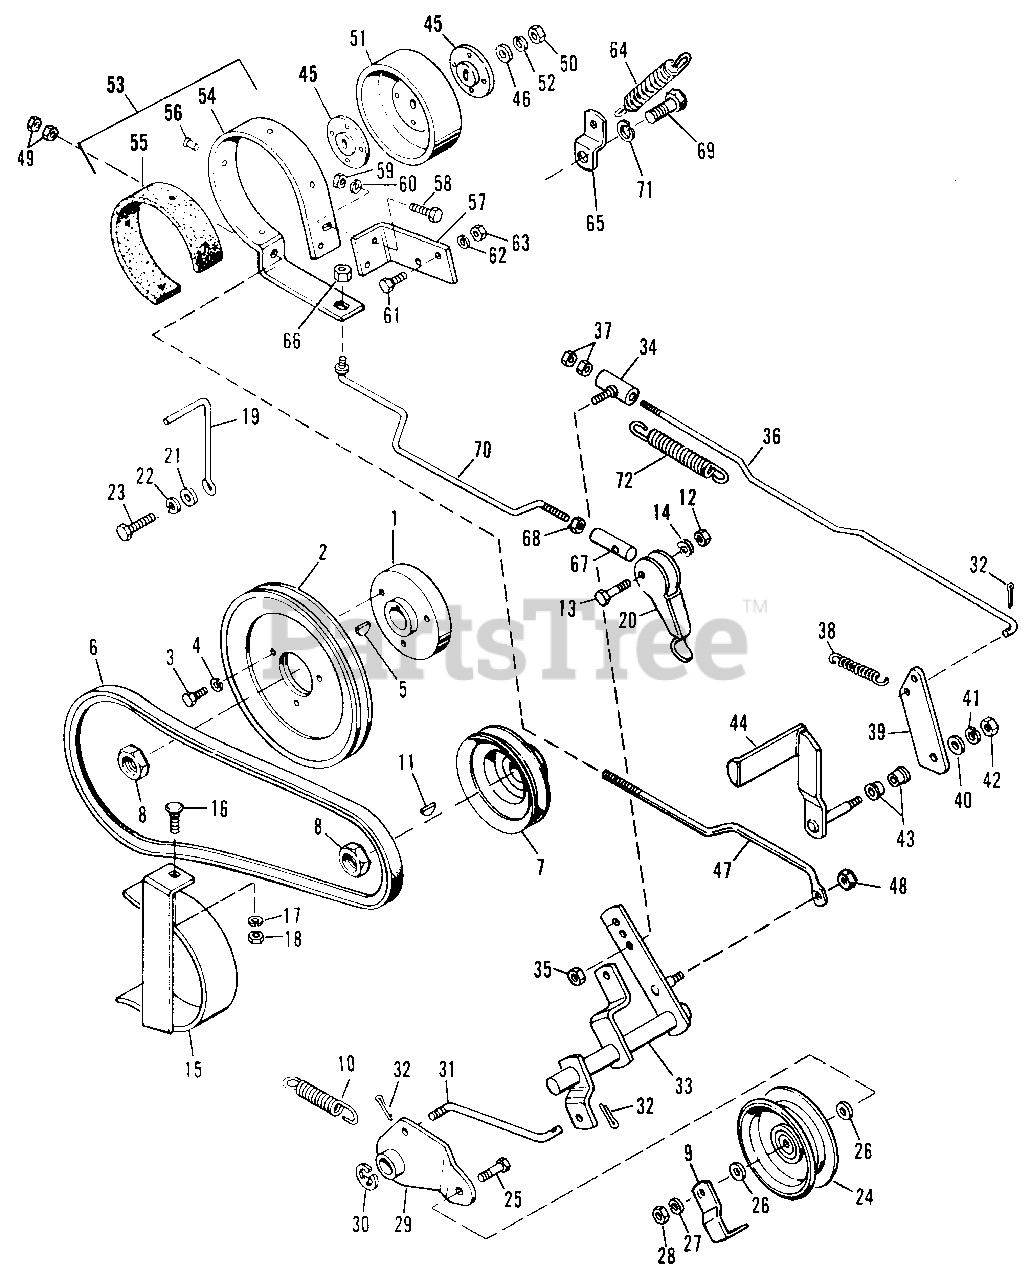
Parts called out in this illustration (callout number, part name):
1	Hub Pulley
2	Pulley Drive
3	Hex Capscrew, 5/16"-18 x 7/8"
4	Lockwasher, 5/16"
5	Key, Woodruff, No. 9
6	V-BELT, 49.1"
8	Hex Jam Nut, 3/4"-16
9	Belt Guide
11	Key, Woodruff, No. 9
12	Full Hex Lock Nut, 1/4"-20
13	Hex Capscrew, 1/4"-20 x 1-1/4"
14	Double Lockwasher, 1/4"
15	Guard Belt Assembly
16	Carriage Bolt, 3/8"-16 x 3/4"
17	Lockwasher, 3/8"
18	Full Hex Nut, 3/8"-16
20	Parking Brake Lever
21	Plain Washer, 3/8"
22	Lockwasher, 3/8"
23	Hex Capscrew, 3/8"-16 x 1"
24	Idler Pulley
25	Hex Capscrew, 3/8"-16 x 1-1/2"
26	Plain Washer, 3/8"
27	Lockwasher, 3/8"
28	Full Hex Nut, 3/8"-16
29	Idler Lever Assembly
30	Retaining Ring
31	Clutch Link
32	Cotter Pin, 3/32" x 3/4"
33	Pivot Lever Assembly
34	Rod Guide Assembly
35	Full Hex Lock Nut, 5/16"-18
36	Brake & Clutch Rod Assy.
37	Full Hex Nut, 5/16"-18
39	Pedal Foot Arm
40	Plain Washer, 3/8"
41	Lockwasher, 3/8"
42	Full Hex Nut, 3/8"-16
44	Foot Pedal Assembly
45	Special Washer
46	Plain Washer, 3/8"
47	Brake Rod
48	Full Hex Nut, 5/16"-18
49	Full Hex Nut, 3/8"-16
50	Full Hex Nut, 7/16"-14
51	Brake Drum
52	Lockwasher, 7/16"
53	Brake Band & Lining Assy.
55	Brake Lining
56	Rivet No. 7 x 5/16"
57	Brake Band Bracket
58	Hex Capscrew, 3/8"-16 x 1"
59	Full Hex Nut, 3/8"-16
60	Lockwasher, 3/8"
61	Hex Capscrew, 1/4"-20 x 3/4"
62	Lockwasher, 1/4"
63	Full Hex Nut, 1/4"-20
64	Tension Spring
65	Spring Clip
66	Full Hex Nut, 5/16"-18
68	Full Hex Lock Nut, 5/16"-18
69	Hex Capscrew, 7/16"-14 x 1-1/4"
70	Parking Brake Rod Assembly
71	Lockwasher, 7/16"
